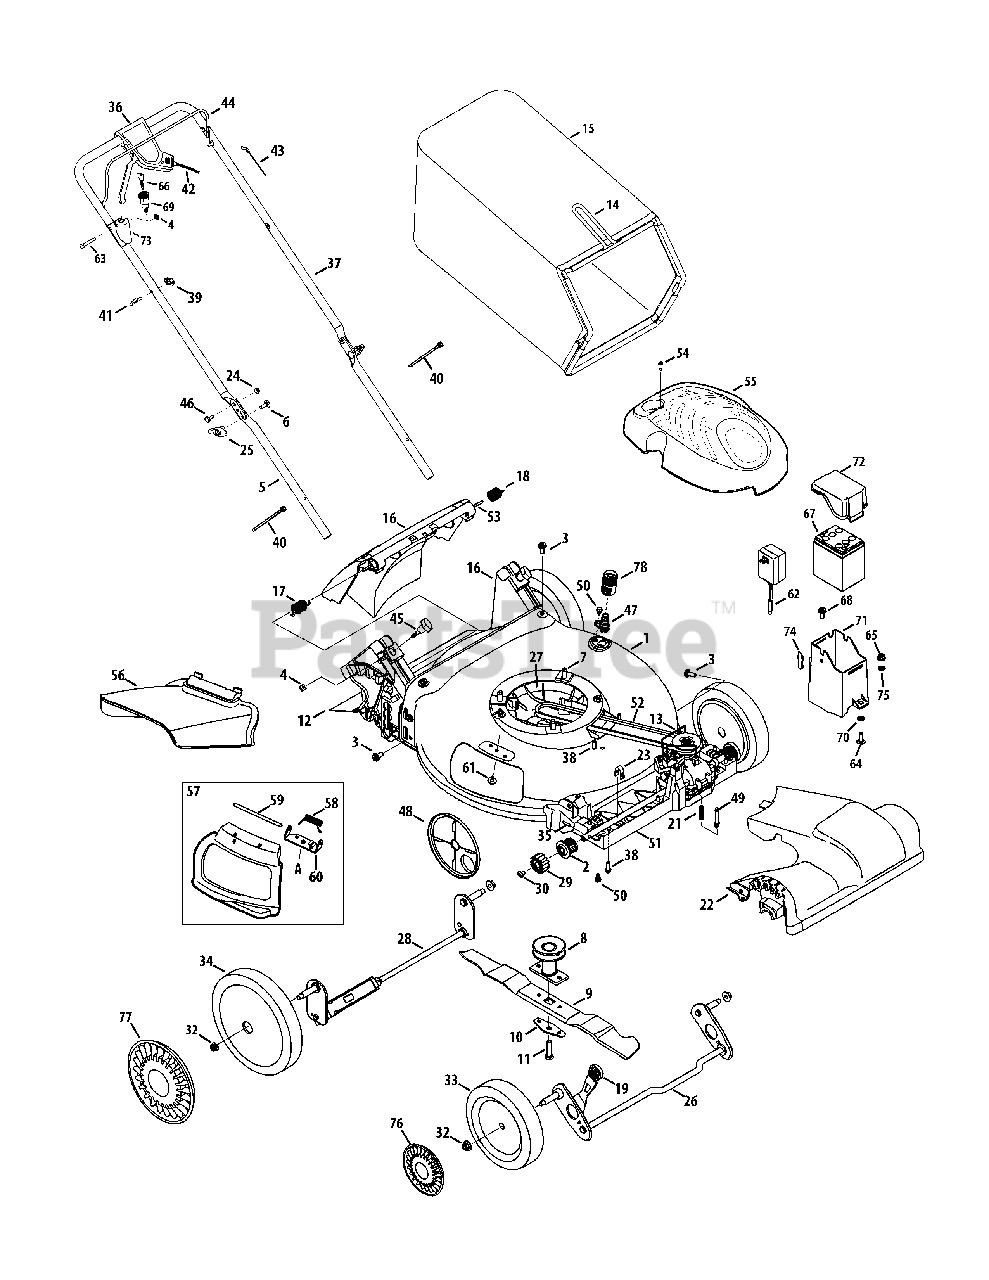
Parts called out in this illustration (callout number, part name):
1	Deck , 21"
2	Bearing Assembly
3	Screw, 5/16-14 x .750
4	Nut, Sq., 1/4-20
5	Lower Handle
6	Carriage Screw ,5/16-18
7	Screw, 3/8-16 x 1.00
8	Blade Adapter
9	Mulching Blade
10	Blade Bell Support
11	Screw, 3/8-24 x 1.50
12	Trailing Shield
13	Transmission Wire
14	Grass Catcher Frame
15	Grass Bag
16	Rear Discharge Door Assembly
17	Torsion Spring - RH
18	Torsion Spring - LH
19	Adjustment Lever Knob
21	Compression Spring
23	Front Axle Clip
24	Nut, Flange Lock, 1/4-20
25	Wing Knob
26	Front Axle Assembly
27	Engine Baffle
28	Rear Axle Assembly
29	Spur Gear, 14T - RH
29	Spur Gear, 14T - LH
30	Screw, 1/4-20 x .390
32	Flange Lock Nut, 3/8-16
33	Front Wheel
34	Rear Wheel
35	Dowel Pin
36	Control Lever Assembly
37	Upper Handle
38	Screw, 1/4-15 x .750
40	Cable Tie
41	Rope Guide
42	Drive Cable
43	Control Cable
45	Wing Nut
46	Sldr. Screw, .375 x .126 x 1/4-20
47	Water Nozzle
48	Wheel Dust Cover
49	Spring Body
50	Scr., Shldr., 1/4-20 x .50
51	Lower Tray
52	V-Belt
53	Pivot Rod
54	Screw, #12-16 x 1.00
55	Engine Shroud, Oyster Gray
56	Side Discharge Chute
57	Mulch Plug (Incl. 58-60)
58	Torsion Spring
59	Hinge Pin
60	Chute Deflector Bracket
61	Screw, 1/4-20 x .500
62	Battery Charger
63	Screw, 1/4-20 x 1.75
64	Bolt, Carr., 5/16-18 x 1.00
65	Nut, Hexlk, 5/16-18
67	Battery
68	Scr., Sldr., 5/16-14 x .972
69	Key Switch
70	Speed Nut
71	Battery Housing
72	Battery Housing Top
73	Electric Start Housing
74	Lid Seal
75	Washer, Bell, .340 x .872 x .080
76	Hubcap, Grey
76	Hubcap, Yellow
77	Hubcap, 11", Grey
78	Water Nozzle Adapter
